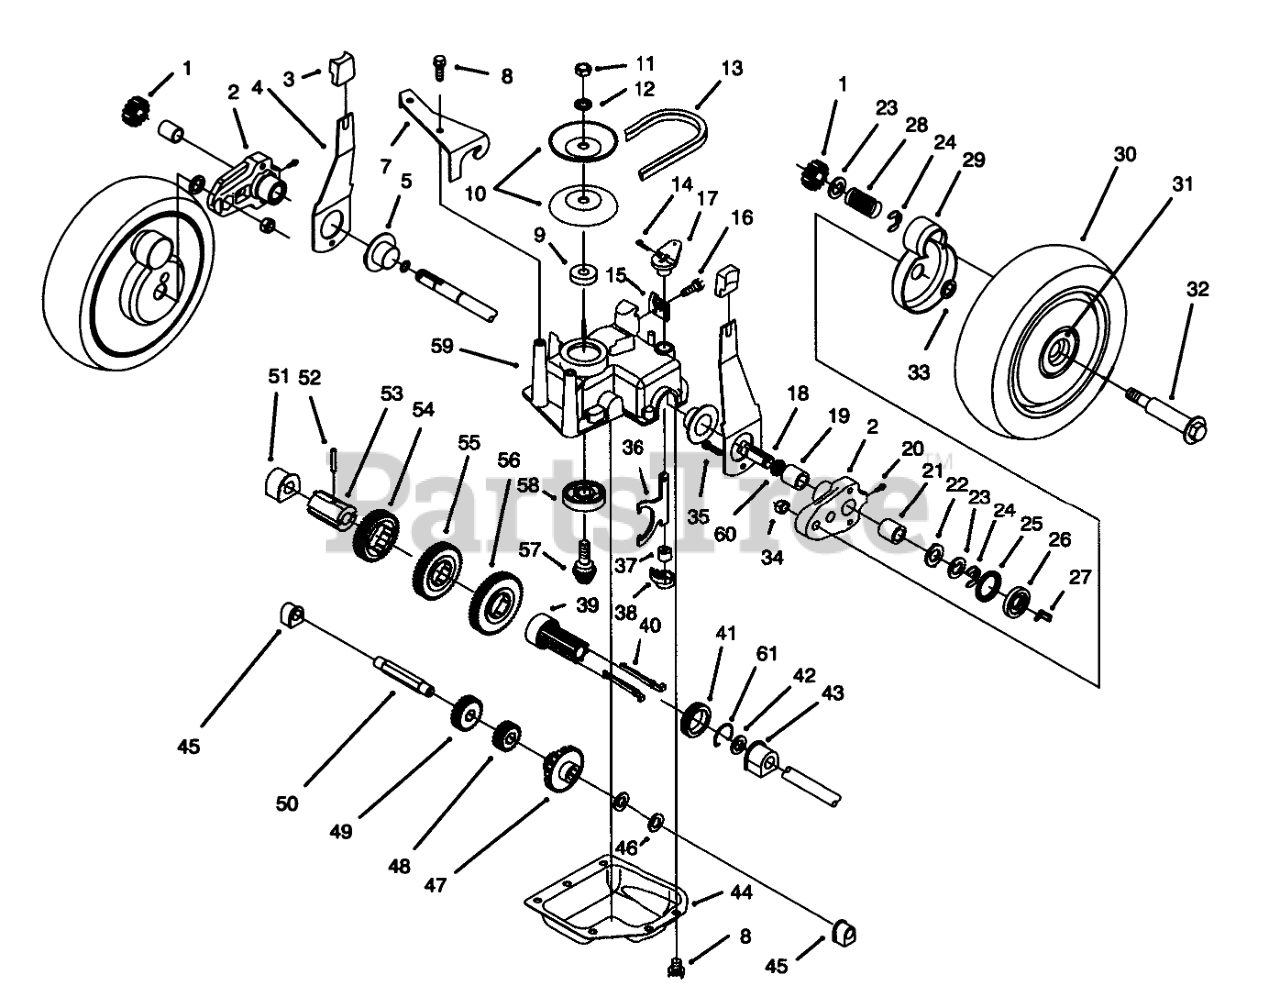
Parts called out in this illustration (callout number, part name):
1	GEAR-PINION
2	Pivot Arm Assembly (Incl. Ref#19,20, & 21)
3	KNOB-ARM
4	SPRING ARM ASM
5	CAP-END
7	Bracket-Guide
8	SCREW-HWHTF
9	SPACER
10	Pulley Half
11	NUT-HEX
12	WASHER-FLAT
13	V-BELT E
14	PIN-COTTER
15	CLAMP-CABLE
16	SCREW-HWHTF
17	LEVER-SHIFT
18	SHAFT-OUTPUT
19	BUSHING
20	FITTING-GREASE
21	BEARING-ROLLER
22	WASHER-ARM, PIVOT
23	WASHER-THRUST, KEYED
24	RING-CLIP, LOCKING
25	RING-FRICTION
26	WASHER-CLUTCH
27	KEY-ROCKING, LH
28	SPRING-COMPRESSION
29	COVER-WHEEL
30	Wheel-Tire & Gear Ass-y (Incl. Ref. #31)
31	BUSHING
32	BOLT-WHEEL
33	SPACER-COVER, WHEEL
34	NUT-LOCK
35	SCREW-HWH
36	YOKE-SHIFT
37	BUSHING-YOKE
38	RETAINER-FORK, SHIFT
39	SLEEVE-KEY, SHIFT
40	KEY-SHIFT
41	COLLAR-SHIFT
42	WASHER-PLAIN
43	BUSHING-OUTPUT
44	Cover-Gearcase
45	BUSHING
46	WASHER-THRUST
47	Gear-Bevel
48	PINION-20T
49	PINION-25T
50	SHAFT-INTERMEDIATE
51	BUSHING
52	PIN-SPRING
53	SLEEVE-GEAR
54	GEAR-39T
55	GEAR-44T
56	GEAR-49T
57	Gear-Pinion
58	BEARING-BALL
59	CASE-GEAR, UPPER
60	O-RING
61	CLIP-SPRING
